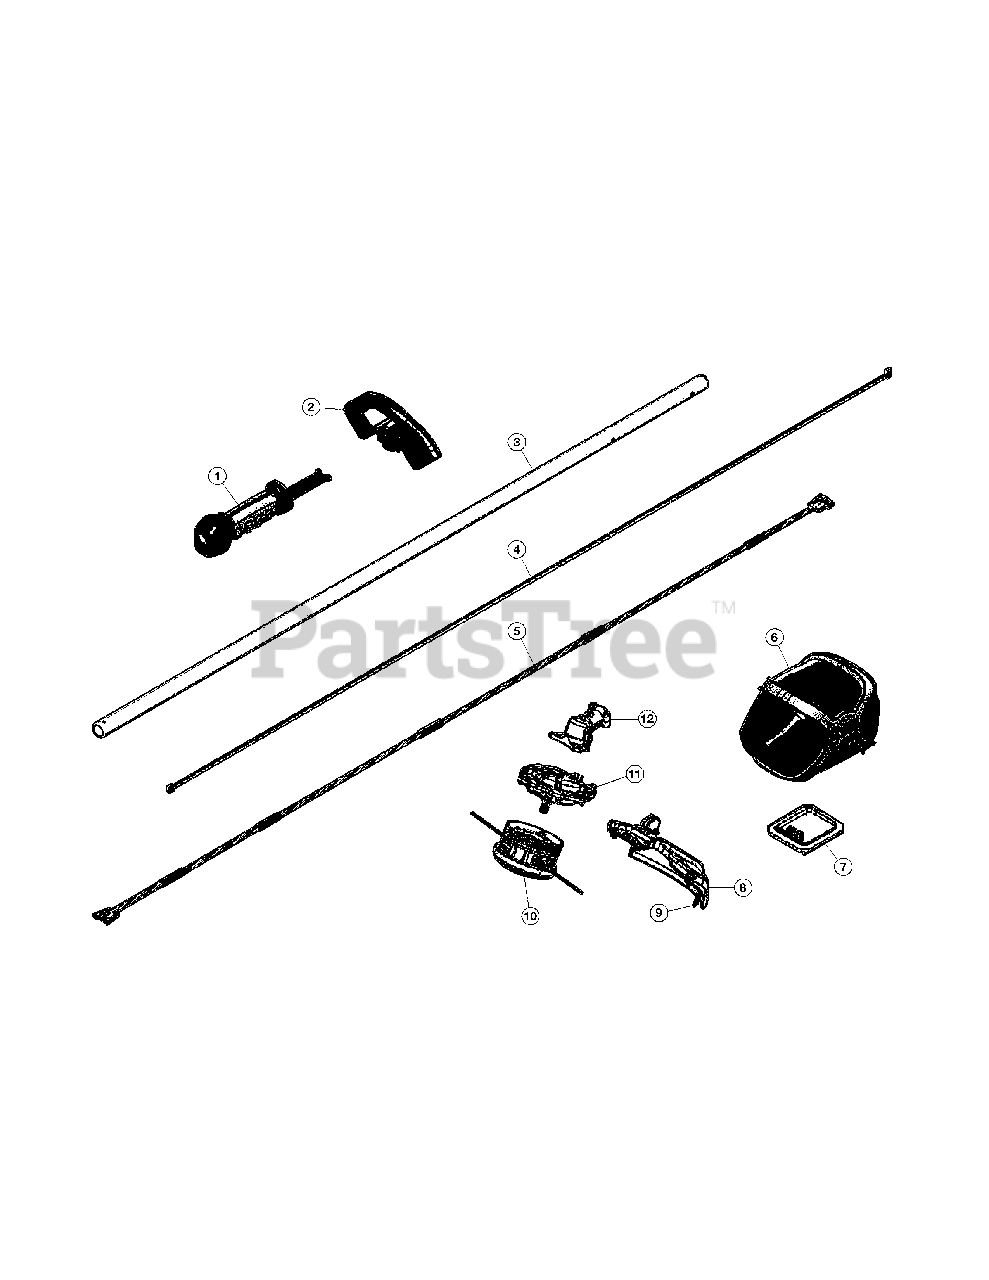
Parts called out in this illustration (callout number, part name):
1	Elite Grip Handle Assembly with Switch Wires
2	Assist Handle Assembly
3	Elite Trimmer Shaft Assembly
4	Hall Wire Assembly
5	Phase Wire Assembly
6	Elite Power Housing Assembly
7	Elite Controller PCB Assembly
8	String Guard Assembly
9	Cut Off Blade
10	Elite Feed Bumphead with Weedwrap
11	Elite Motor Assembly
12	Elite Yoke
